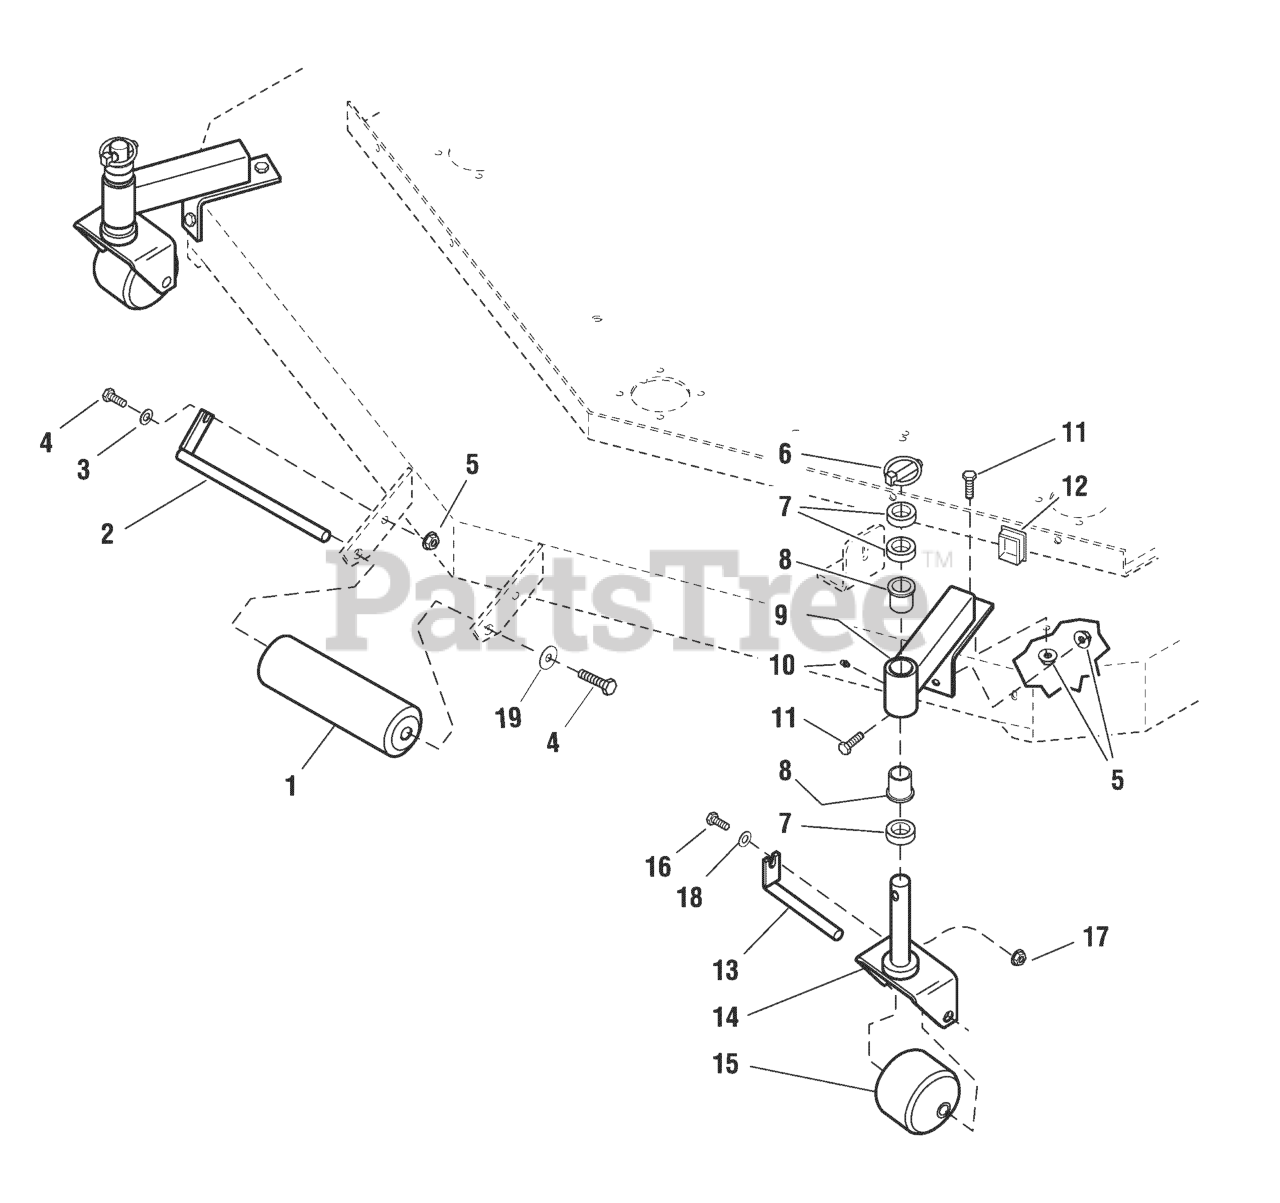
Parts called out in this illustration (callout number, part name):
1	ROLLER
3	WASHER, 3/8 SAE
4	BOLT, 3/8-16 X 1" GD5 CZ
5	NUT, 3/8-16 Hex Serrated Flange
6	PIN, Lynch
7	SPACER, 1.02 x 1.56 x .50
8	BUSHING, FLANGE
9	CASTER MOUNT ARM
10	GREASE FITTING
11	BOLT, 3/8-16 X 3/4" GD5 CZ
12	CAP, Plastic
13	CASTER ROLLER PIN
14	CASTER YOKE
15	ROLLER, Caster
16	BOLT, 5/16-18 X 3/4 GD5
17	NUT, 5/16-18 HEX SERRATED FLANGE (SMALL)
18	WASHER, 5/16" GD9
19	WASHER, .390 X 1.50 X .109 YZ
